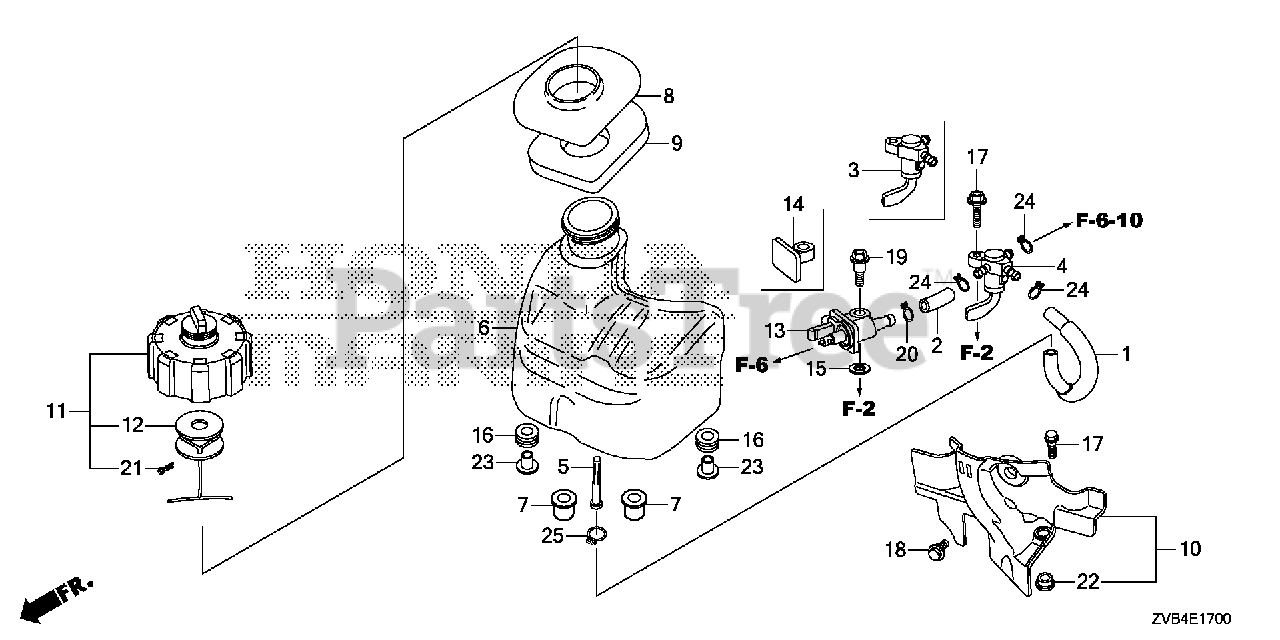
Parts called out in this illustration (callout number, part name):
1	TUBE A, FUEL
2	TUBE B, FUEL
4	PETCOCK ASSY. (THREE-WAY)
5	FILTER, FUEL
6	TANK, FUEL (COO)
7	RUBBER, TANK MOUNTING
8	RUBBER, TANK CAP
9	SEAL, FUEL TANK
10	INSULATOR, FUEL TANK
11	CAP-TETHER ASSY., FUEL TANK
12	TETHER, FUEL CAP
13	CONNECTOR ASSY., FUEL (B)
15	WASHER, PLAIN (6MM)
16	GROMMET, ELECTRONIC PARTS CASE
17	BOLT, FLANGE (6X20)
18	BOLT, SPECIAL (6MM)
19	BOLT, SPECIAL (6X22) (CT200)
20	CLIP, TUBE (B1 11)
21	PIN, LOCK (5MM)
22	COLLAR, FUEL TANK INSULATOR
23	COLLAR, MODULE IGNITION CONTROL CASE (CDI)
24	CLIP, TUBE (B1 10)
25	CLIP, TUBE (B1 12)
